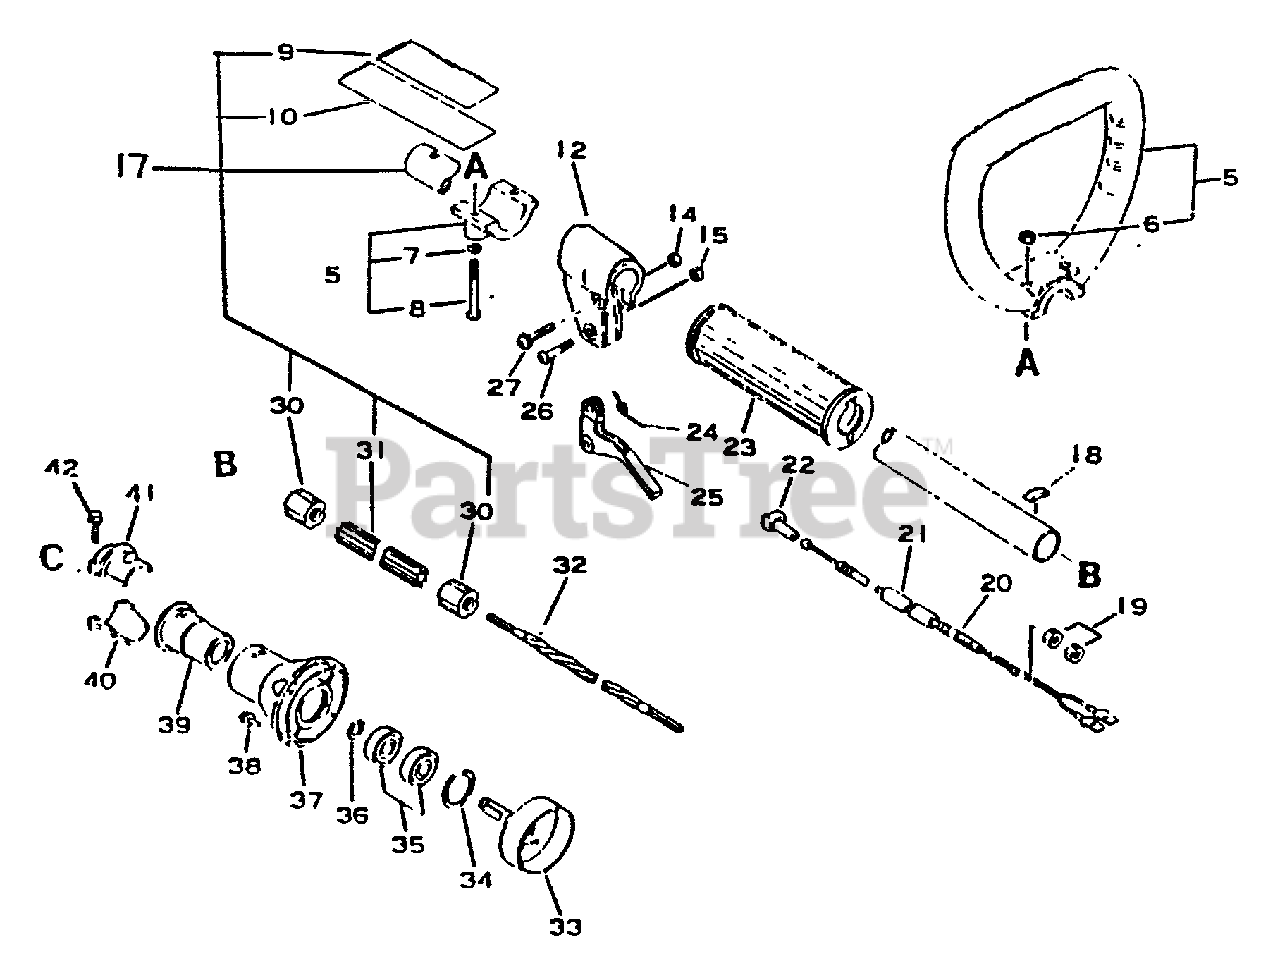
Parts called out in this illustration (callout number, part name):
5	LOOP HANDLE ASSY
6	NUT M5
7	WASHER, FLAT 5.5×10×0.8
8	SCREW 5×40
9	LABEL - CAUTION
10	LABEL - CAUTION
12	BRACKET, TRIGGER
14	NUT M5
15	LOCKNUT - 5
17	MAIN PIPE ASSY
18	LABEL - ALIGNMENT
20	CABLE, THROTTLE
22	GUIDE, CABLE
23	GRIP, HANDLE
24	SPRING, THROTTLE
25	TRIGGER, THROTTLE
27	SCREW 5×30
30	STOPPER
31	LINER - FLEXIBLE
32	DRIVESHAFT - FLEXIBLE
33	DRUM, CLUTCH
34	RING, SNAP 28
35	BEARING, BALL 6001
36	RING, RETAINING - 12
37	CASE, CLUTCH
38	SCREW 5×16
41	HOLDER, MAIN PIPE - UPPER
42	BOLT - 5×25
